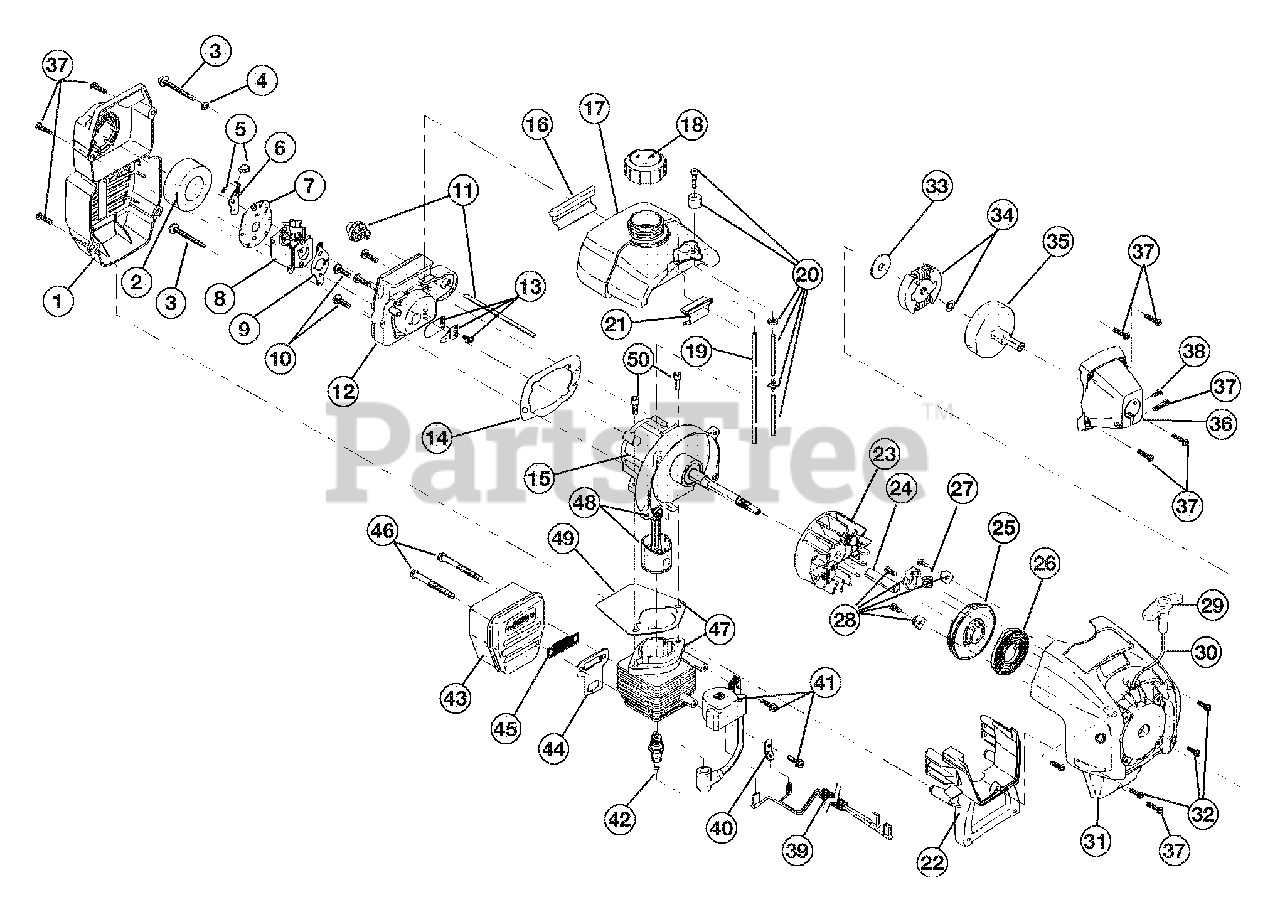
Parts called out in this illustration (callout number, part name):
1	Air Cleaner/Muffler Cover Assembly
2	Air Cleaner Filter
3	Carburetor Mounting Screws
4	Wavey Washer
5	Choke Knob and Screw
6	Choke Lever Assembly
7	Choke Lever and Plate
8	Carburetor Assembly
9	Carburetor Gasket
10	Carb Mount Screw
11	Primer and Hose Assembly
12	Carb Mount Assembly
13	Reed Assembly
14	Carburetor Mount Gasket
15	Crank Case Service Assembly
16	Rear Mounting Pad
17	Fuel Tank Assembly
18	Fuel Cap Assembly
19	Fuel Return Line
20	Fuel Line Assembly
21	Front Mounting Pad
22	Shroud Extension and Stand
23	Flywheel Assembly
25	Recoil Pulley Assembly
26	Recoil Spring
27	Rope Guide
28	Pulley Retainer Assembly
29	Pull Handle
31	Starter Housing Assembly
32	Housing Screw
33	Clutch Washer
34	Clutch Rotor Assembly
35	Clutch Drum Assembly
36	Clutch Cover Assembly
37	Cover Screw
38	Anti-Rotation Screw
39	Wire Leads and Sleeve
40	Ground Tab
41	Module Assembly
42	Spark Plug
43	Muffler Assembly
44	Exhaust Gasket
45	Spark Arrestor
46	Muffler Mounting Bolt Assembly
47	Cylinder Assembly
48	Piston and Rod Assembly
49	Cylinder Gasket
50	Cylinder Bolt
